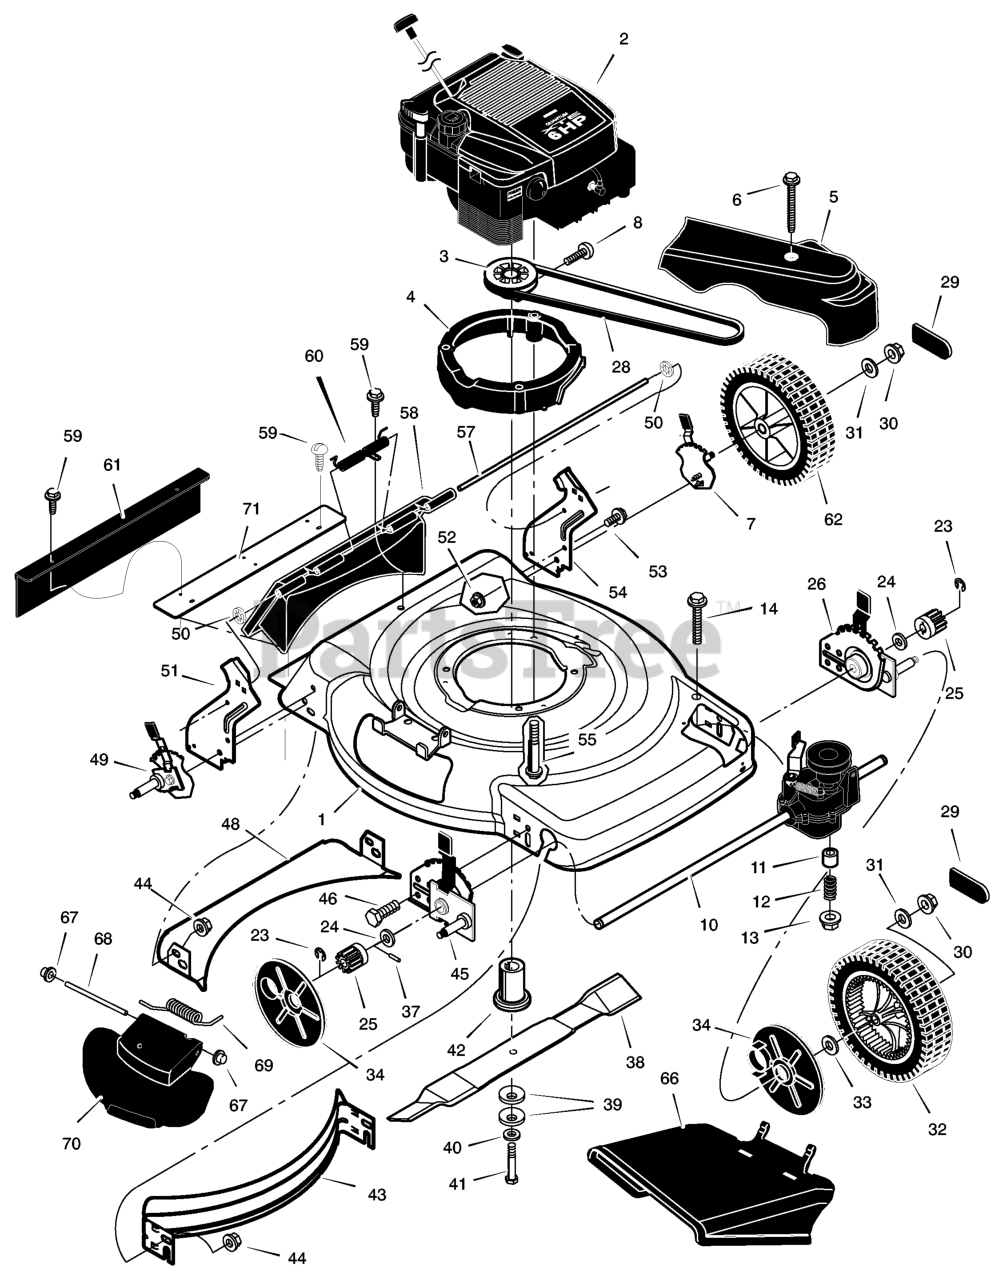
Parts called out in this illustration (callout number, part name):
2	Engine *
3	Pulley, Drive
4	Spacer, Engine
5	Cover, Belt (Gray)
7	Adjuster, Left Rear Height
10	Transmission *
12	Spring, Compression
13	Nut
14	Bolt
25	Gear, Pinion
26	Adjuster, Left Front Height
29	Cap, Hub
30	Nut, Flange
31	Washer
32	Wheel & Tire, Drive
34	Cover, Dust
37	Pin, Drive
39	Washer, Belleville
42	Adapter, Blade
43	Baffle, Front
44	Nut, Flange
45	Adjuster, Right Front Height
46	Bolt
48	Baffle, Rear
49	Adjuster, Right Rear Height
50	Push On Cap
51	Bracket, Right Handle
52	Nut, Flange
53	Bolt
54	Bracket, Left Handle
55	Bolt, Engine
57	Rod, Pivot
58	Door, Rear (Gray)
60	Spring
61	Guard, Rear
62	Wheel & Tire, Rear
66	Deflector, Chute (Gray)
67	Push On Cap
68	Rod, Pivot
69	Spring, Torsion
70	Cover, Mulch (Gray)
71	Extension, Rear
